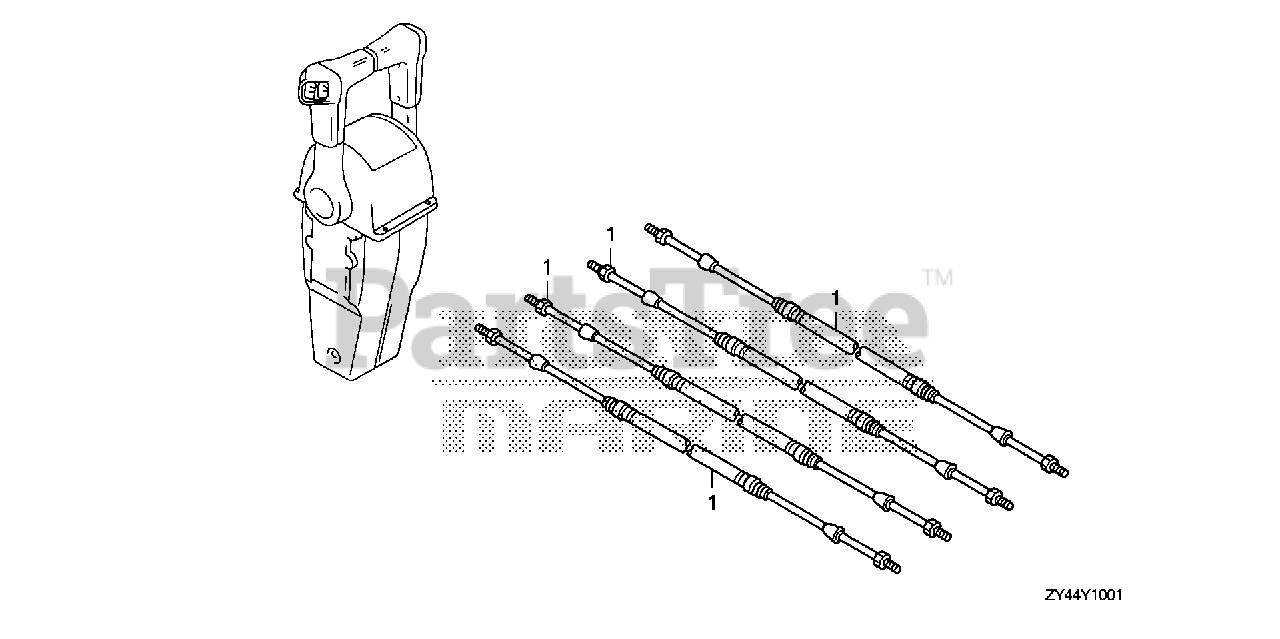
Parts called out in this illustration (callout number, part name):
1	CABLE, REMOTE CONTROL (10') (LOW FRICTION)
1	CABLE ASSY., PUSH-PULL (33C-5FT)
1	CABLE, REMOTE CONTROL (11') (LOW FRICTION)
1	CABLE ASSY., PUSH-PULL (33C-6FT)
1	CABLE, REMOTE CONTROL (12') (LOW FRICTION)
1	CABLE ASSY., PUSH-PULL (33C-7FT)
1	CABLE, REMOTE CONTROL (13') (LOW FRICTION)
1	CABLE ASSY., PUSH-PULL (33C-8FT)
1	CABLE, REMOTE CONTROL (14') (LOW FRICTION)
1	CABLE ASSY., PUSH-PULL (33C-9FT)
1	CABLE, REMOTE CONTROL (15') (LOW FRICTION)
1	CABLE ASSY., PUSH-PULL (33C-10FT)
1	CABLE, REMOTE CONTROL (16') (LOW FRICTION) (NOT AVAILABLE)
1	CABLE ASSY., PUSH-PULL (33C-11FT)
1	CABLE, REMOTE CONTROL (17') (LOW FRICTION)
1	CABLE ASSY., PUSH-PULL (33C-12FT)
1	CABLE, REMOTE CONTROL (18') (LOW FRICTION) (NOT AVAILABLE)
1	CABLE ASSY., PUSH-PULL (33C-13FT)
1	CABLE, REMOTE CONTROL (19') (LOW FRICTION)
1	CABLE ASSY., PUSH-PULL (33C-14FT)
1	CABLE, REMOTE CONTROL (20') (LOW FRICTION) (NOT AVAILABLE)
1	CABLE ASSY., PUSH-PULL (33C-15FT)
1	CABLE, REMOTE CONTROL (21') (LOW FRICTION)
1	CABLE ASSY., PUSH-PULL (33C-16FT)
1	CABLE, REMOTE CONTROL (22') (LOW FRICTION) (NOT AVAILABLE)
1	CABLE ASSY., PUSH-PULL (33C-17FT)
1	CABLE, REMOTE CONTROL (23') (LOW FRICTION)
1	CABLE ASSY., PUSH-PULL (33C-18FT)
1	CABLE, REMOTE CONTROL (24') (LOW FRICTION) (NOT AVAILABLE)
1	CABLE ASSY., PUSH-PULL (33C-19FT)
1	CABLE, REMOTE CONTROL (25') (LOW FRICTION)
1	CABLE ASSY., PUSH-PULL (33C-20FT)
1	CABLE, REMOTE CONTROL (26') (LOW FRICTION)
1	CABLE ASSY., PUSH-PULL (33C-21FT)
1	CABLE, REMOTE CONTROL (27') (LOW FRICTION)
1	CABLE ASSY., PUSH-PULL (33C-22FT)
1	CABLE, REMOTE CONTROL (28') (LOW FRICTION) (NOT AVAILABLE)
1	CABLE ASSY., PUSH-PULL (33C-23FT)
1	CABLE, REMOTE CONTROL (29') (LOW FRICTION)
1	CABLE ASSY., PUSH-PULL (33C-24FT)
1	CABLE, REMOTE CONTROL (30') (LOW FRICTION) (NOT AVAILABLE)
1	CABLE ASSY., PUSH-PULL (33C-25FT)
1	CABLE, REMOTE CONTROL (31') (LOW FRICTION)
1	CABLE ASSY., PUSH-PULL (33C-26FT)
1	CABLE, REMOTE CONTROL (32') (LOW FRICTION) (NOT AVAILABLE)
1	CABLE ASSY., PUSH-PULL (33C-27FT)
1	CABLE, REMOTE CONTROL (33') (LOW FRICTION)
1	CABLE ASSY., PUSH-PULL (33C-28FT)
1	CABLE, REMOTE CONTROL (34') (LOW FRICTION) (NOT AVAILABLE)
1	CABLE ASSY., PUSH-PULL (33C-29FT)
1	CABLE, REMOTE CONTROL (35') (LOW FRICTION)
1	CABLE ASSY., PUSH-PULL (33C-30FT)
1	CABLE ASSY., PUSH-PULL (33C-31FT)
1	CABLE ASSY., PUSH-PULL (33C-32FT)
